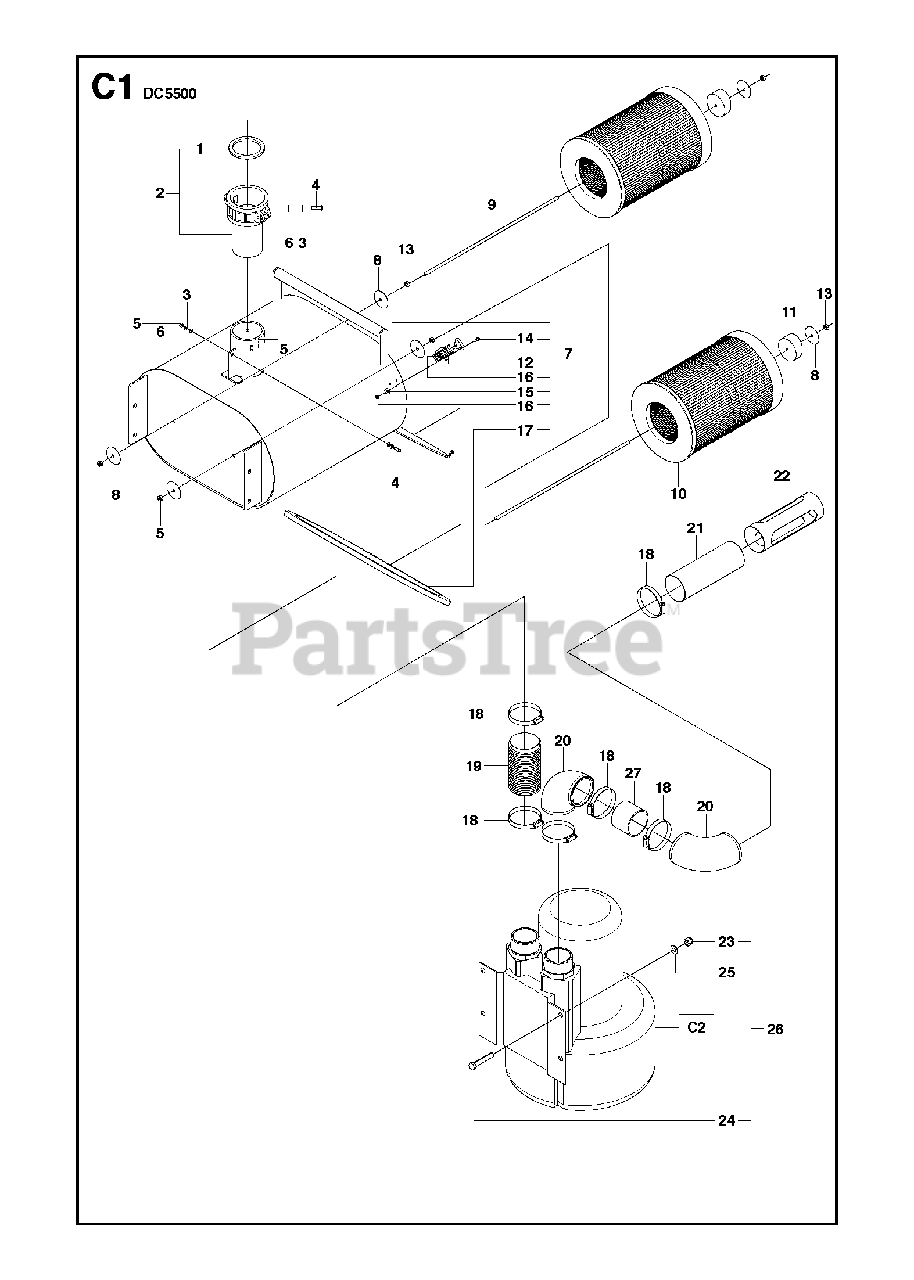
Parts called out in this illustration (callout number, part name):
3	WASHER
5	HEXAGON LOCKING NUT
13	HEXAGON NUT
16	HEXAGON LOCKING NUT
25	WASHER
